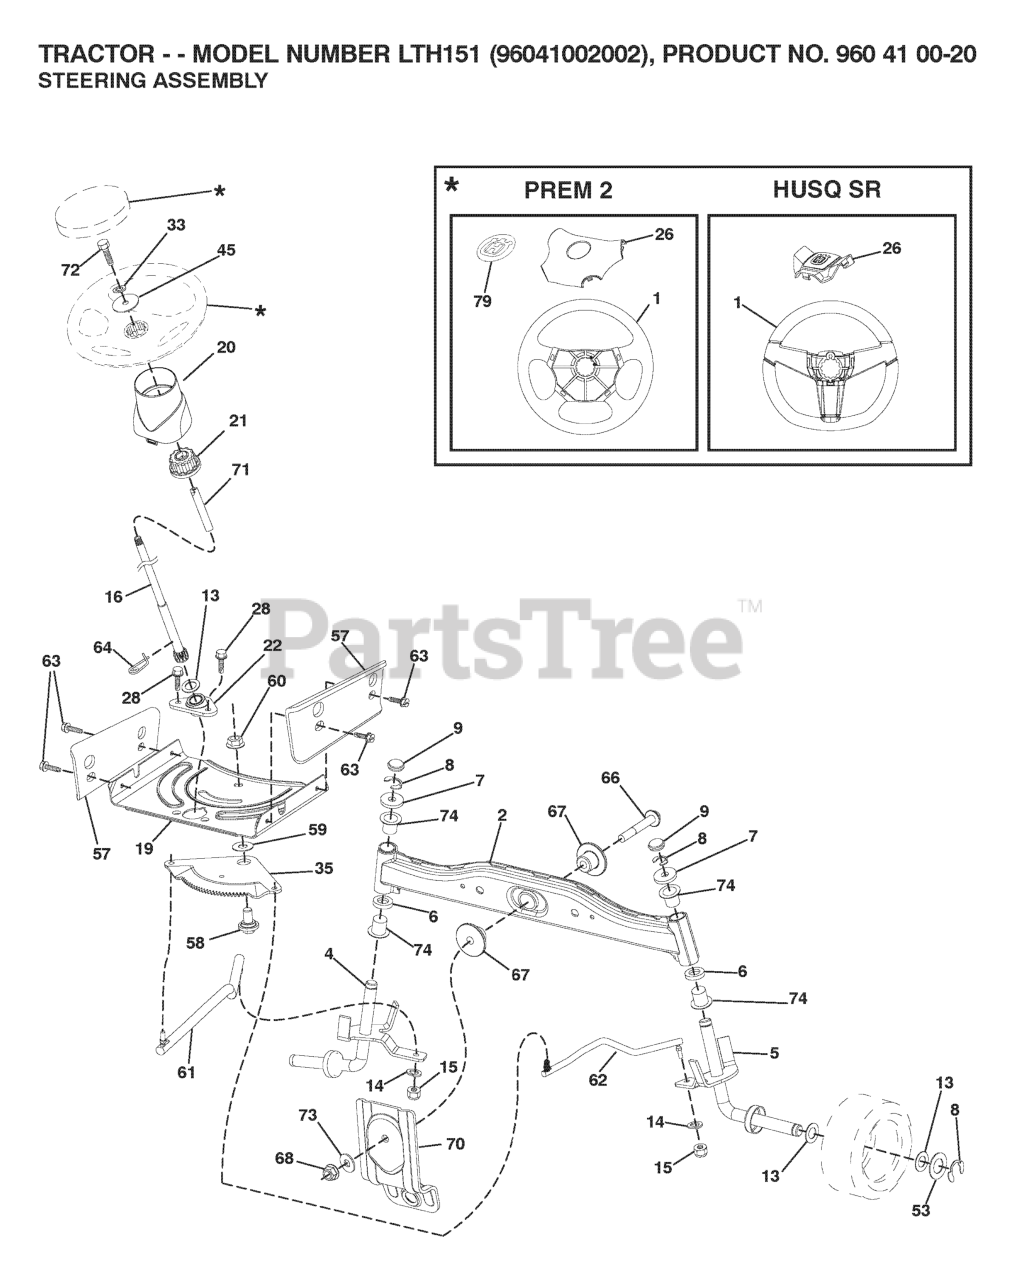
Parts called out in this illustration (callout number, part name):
1	RP WHEEL.STEER.HUSQ.PREM.OVMLD
2	AXLE.HALF.ASM.WELDED
4	SPINDLE.WELDED.LH.15"TEX
5	SPINDLE.WELDED.RH.15"T
6	THRUST WASHER
9	CAP.SPINDLE.BLACK
14	WASHER, LOCK 3/8
15	NUT CROWNLOCK 3/8-24
16	SHAFT STEERING
19	PLATE.STEER.DDL.NLT/NG
20	BOOT, STEERING
21	ADAPTER, WHEEL STNG..
22	BUSHING.ASM.STEERING.A
26	RP INSERT.CAP.WHL.STRG.HUSQ.
28	SCREW, 3/8-16X3/4
33	WASHER.LOCK.HVY.HLCL.SPR.5/16
35	GEAR.SECTOR.PLATE.DDL.
45	WASHER.11/32
53	WASHER.HARDENED
57	BRACKET.UPSTOP.TEX
58	BOLT.SHOULDER.SECTOR.P
59	WASHER.THURST.SECTOR.S
60	NUT FLANGE LOCK 5/8-11
61	DRAGLINK.LH.BALLSTUD.D
62	DRAGLINK.RH.BALLSTUD.D
63	SCREW
64	RETAINER.CLIP.SPRING.S
66	BOLT HEX FGHD 7/16-14 X 3 SERR
67	BUSHING.PM.FRONT AXLE
68	NUT.LOCK.FLANGE.7/16
70	BRKT.DECK.SUSPENSION.F
71	SHAFT EXTENSION STEERING
72	BOLT YT
73	WASHER.1.5X.505X.118
74	BRNG T
